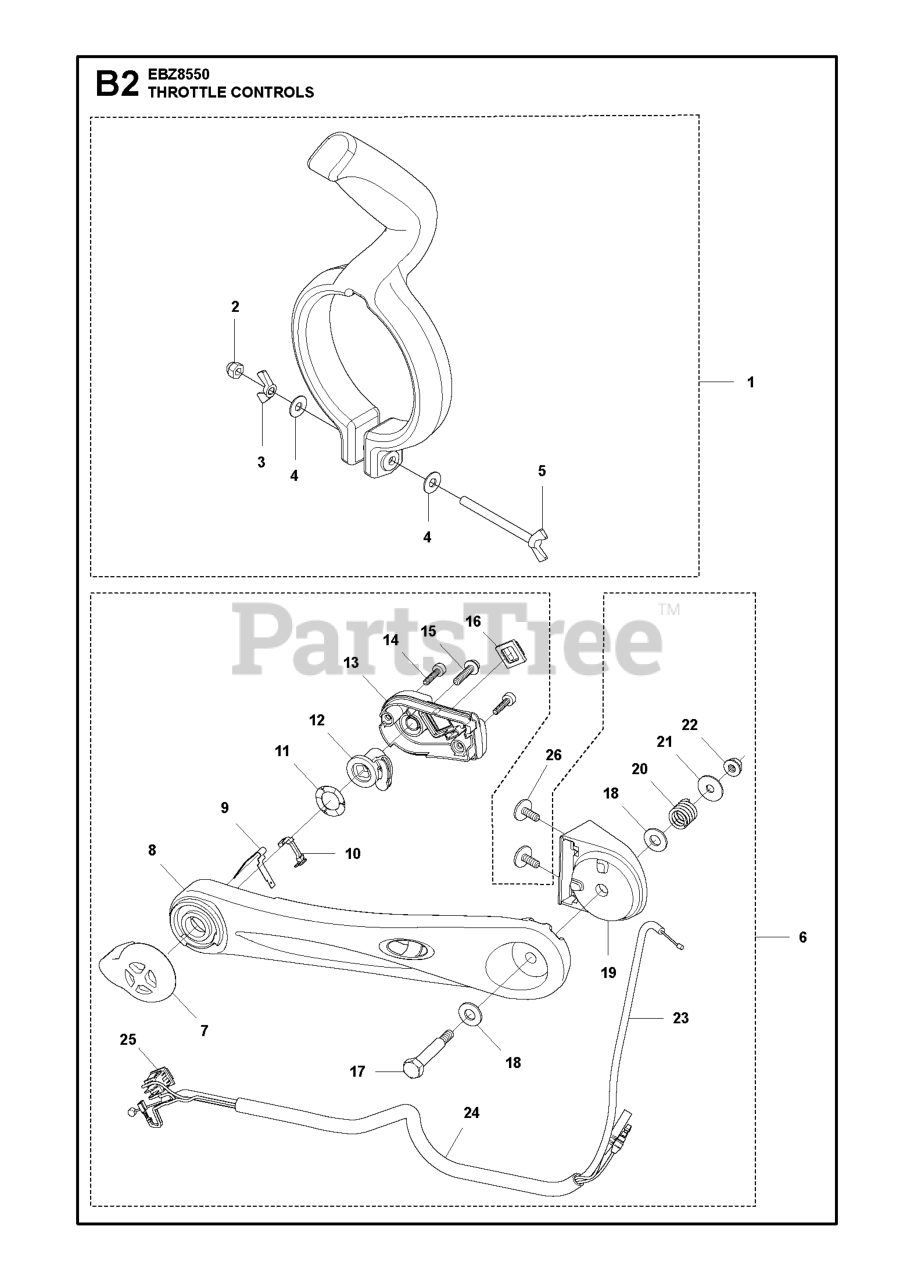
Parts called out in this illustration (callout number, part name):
3	WING NUT
4	WASHER
5	WING BOLT
6	LEVER,SET
7	LEVER,THROTTLE
9	PLATE, CONTACT
11	WASHER WAVE
15	BOLT
16	CAP SWITCH
21	WASHER Z349525440
22	NUT 8488646000
